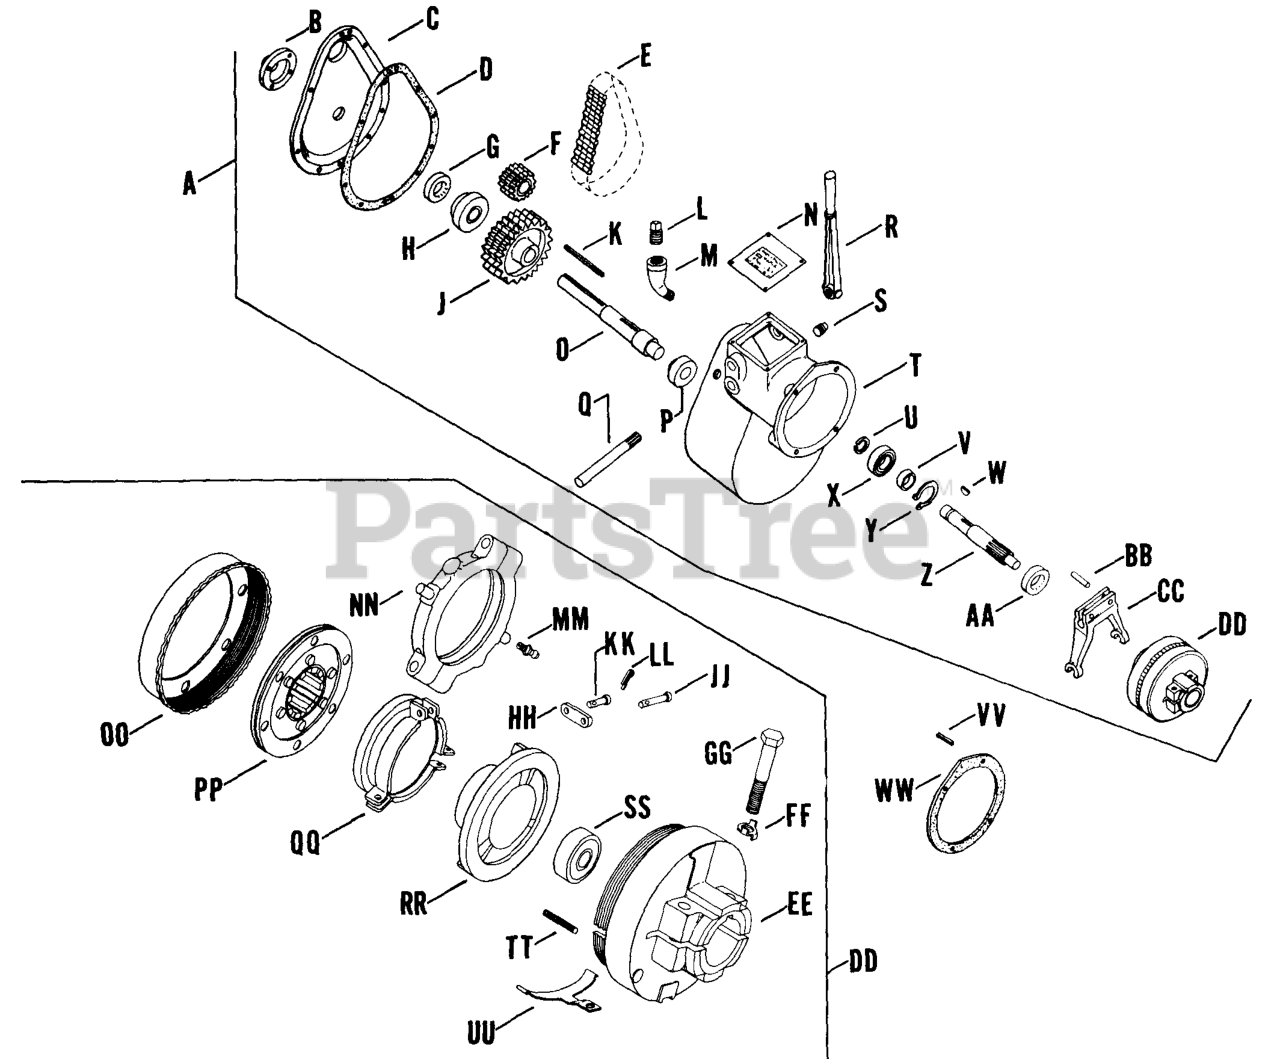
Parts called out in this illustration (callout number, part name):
A	Reduction, gear - assembly (with clutch) (Includes B thru DD)
L	PLUG, SQ HD PIPE 3/8" USE 25 139 57-S
M	Elbow, street 3/8
Q	SHAFT - DISCONTINUED
R	LEVER - DISCONTINUED
S	Plug, drain 3/8
T	Housing, clutch and gear
U	SNAP RING - DISCONTINUED
CC	YOKE - USE 24 471 01
EE	HOUSING - DISCONTINUED
FF	LOCK - DISCONTINUED
HH	LINK - DISCONTINUED
JJ	PIN - DISCONTINUED
OO	RING - DISCONTINUED
PP	MEMBER - DISCONTINUED
SS	BEARING
TT	SPRING - DISCONTINUED
VV	KEY - DISCONTINUED
